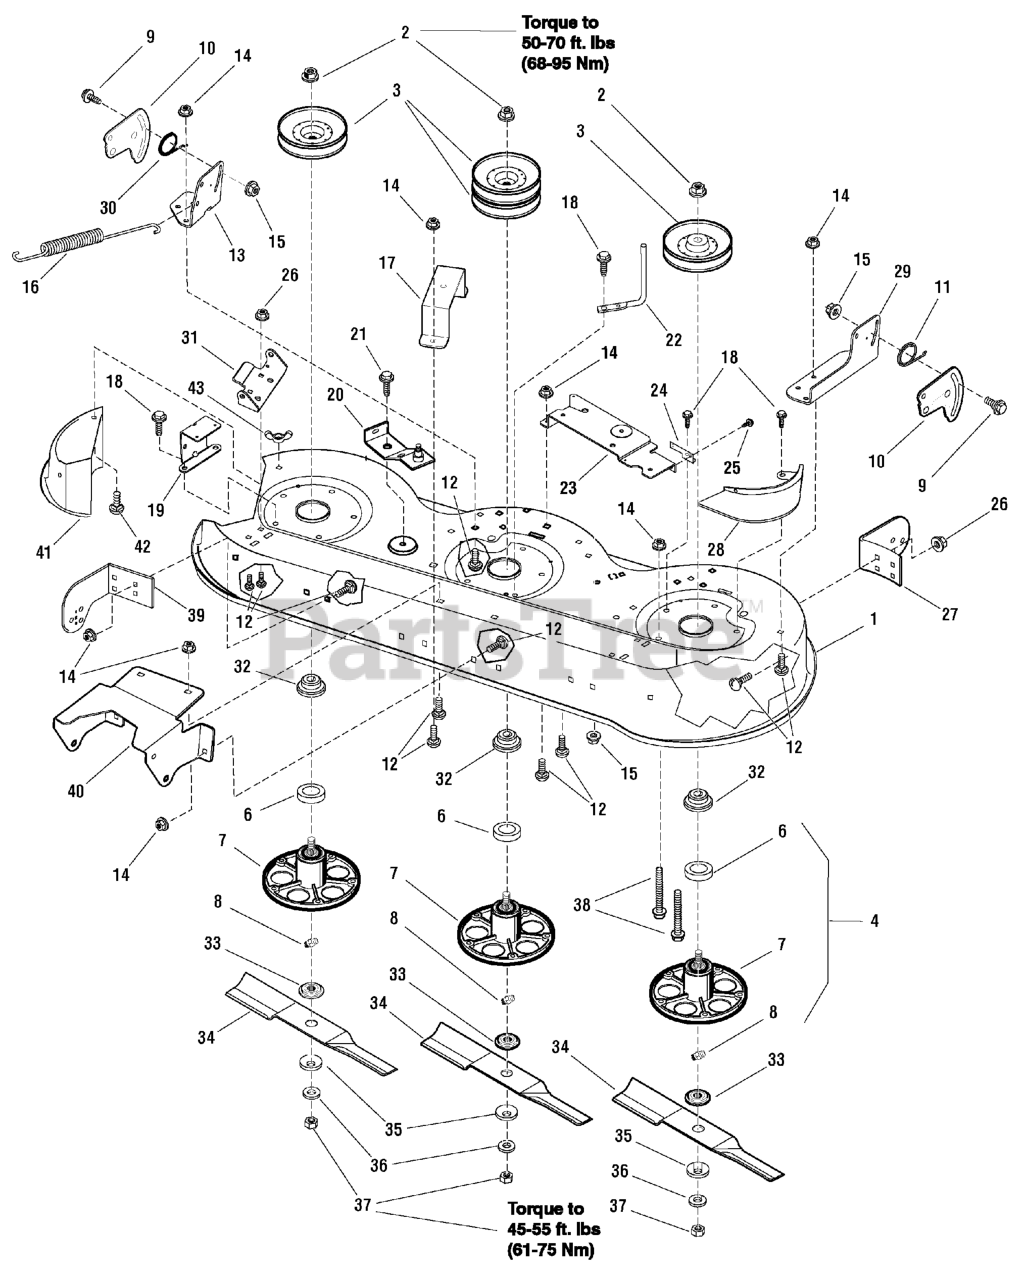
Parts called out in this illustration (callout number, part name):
1	HOUSING, Mower, 46 in
2	NUT, Nylock Ring, Pulley 9/16-18
3	PULLEY, Split Steel
4	JACKSHAFT HOUSING ASSY
6	BALL BEARING, Jackshaft
7	JACKSHAFT HOUSING
8	FITTING, Lubrication
9	BOLT, Shoulder, 3/8-16 x 1
10	BRACKET, Deck Suspension
11	SPRING, Right Torsion
12	BOLT, Carriage, 5/16-18 x 5/8
13	BRACKET, Right Rear
14	NUT, Hex Flange 5/16-18
15	NUT, Hex Flange, 3/8-16
17	BRACKET, Bellcrank
18	SCREW, Thread Forming 3/8-16 x 1-1/4
19	BRACKET, Cover
20	IDLER ARM, 46", Right
21	BOLT, Shoulder 3/8-16 x 3/4
22	GUIDE, Belt
23	BRACKET, Brake Mounting 46 in
24	BRACKET, Brake Plate
25	CAPSCREW, 5/16-18
26	NUT, Hex Flange Lock, 5/16-18
27	BRACKET, Left Gauge Wheel
28	BRACKET, Pulley Cover
29	BRACKET, Left Lift
30	SPRING, Left Torsion
31	BRACKET, Hinge
32	SPACER, Pulley
33	BLADE ADAPTER
34	BLADE, 46 in
35	WASHER, Belleville
36	WASHER, Hardened 1
37	NUT, Blade, 9/16-18
38	GUIDE, SCREW (5/16-18)
39	BRACKET, Right Gauge Wheel
40	BRACKET, Front Deck
41	COVER, Mulch
42	BOLT, Carriage 5/16-18 x 3/4
43	WINGNUT, 5/16-18
